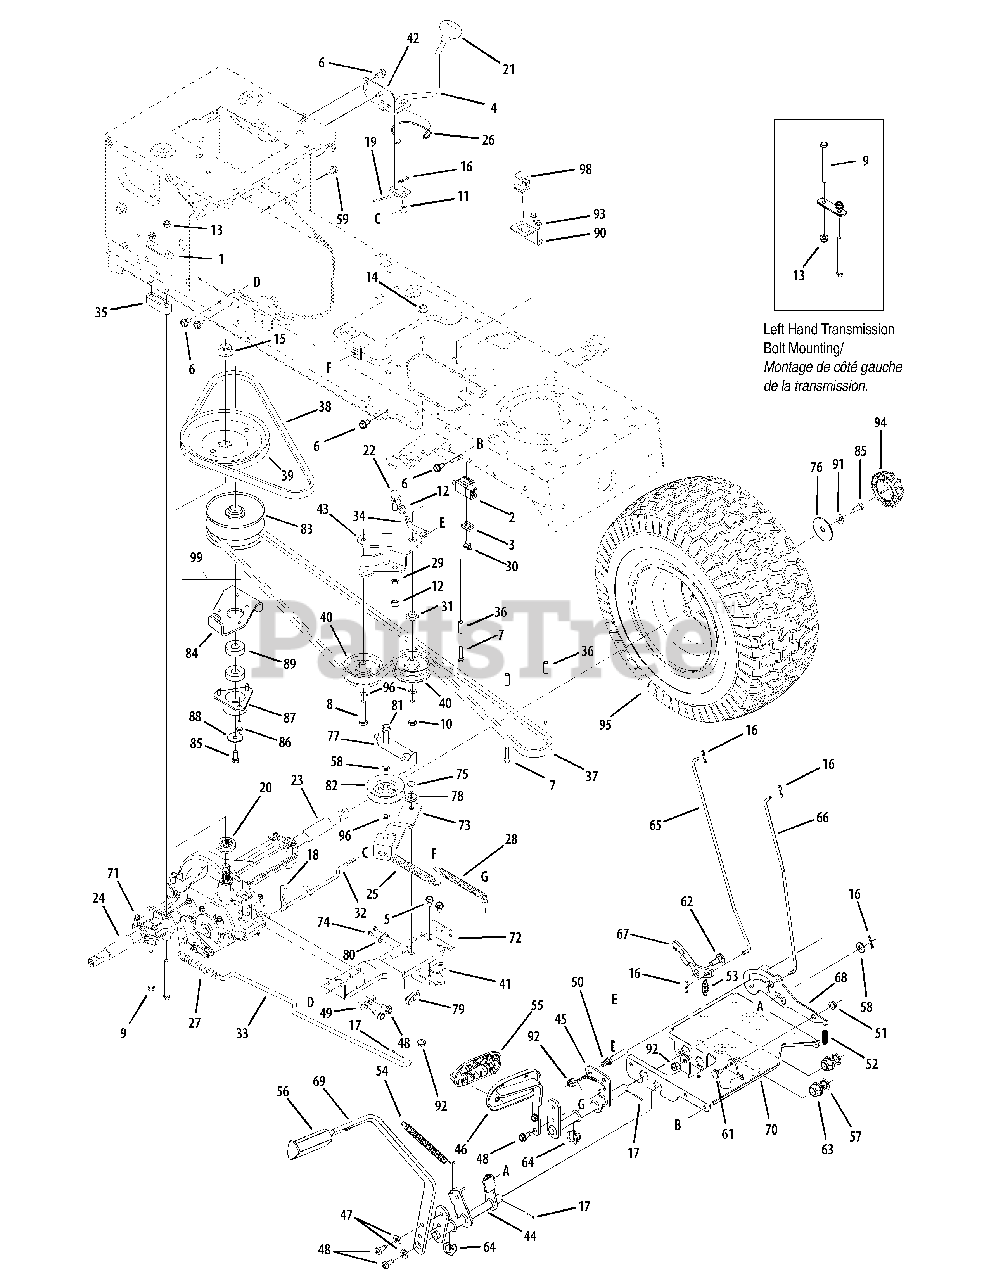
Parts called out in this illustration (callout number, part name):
2	Interlock Switch
3	Switch Plate
4	Shift Lever Ass’y
5	Hex Wash HD S-Tapp Scr 5/16-18 x .50
6	S-Tapp Scr 5/16-18 x .75
7	Hex Bolt 1/4-20 x 1.25
8	Hex L-Wash HD Scr 3/8-16 x 1.5
9	Hex Bolt 5/16-18 x 3.5" Lg.
10	Hex Bolt 3/8-16 x 2.0" Lg. Gr. 5
11	Adjustment ferrule
12	Hex Nut 3/8-24
13	Flange Locknut 5/16-18 Gr. F, Nylon
14	Flange Locknut 3/8-16 Gr. F
16	Int. Cotter Pin .072 x 1.13" Lg.
17	Cotter Pin 3/32 dia x 1.00 Lg.
18	Cotter Pin
19	Cotter Pin 1/8" Dia x 1.25
20	Pulley Hub 5/8" Spline
22	Drag Link Ball Joint
23	Sleeve, .758 x .821 x 3.3125
24	Sleeve, .758 x .821 x 2.4375
25	Extension Spring .62 dia. x 6.12
26	Complete Spring Clip
27	Extension Spring .59 x 4.0
28	Extension Spring, .50 Dia. x 6.37
29	L-Wash 3/8 ID
30	Hex AB-Tap Scr #10 x .50" Lg.
31	Shoulder Spacer
34	Idler Adjustment Rod, 3/8
35	Transaxle Spacer
36	Spacer .260 x .375 x 1.030 Lg.
37	Variable-speed Belt
38	Drive Belt
39	Pulley, V-Type, 7.25 dia.
40	Idler Pulley, Flat 2.75 OD
41	Shift Bracket
42	Shift Bracket F-N-R
47	L-Wash 5/16 ID
48	Hex Wash. Hd. Scr. 5/16-18 x .75 Lg.
49	Flat Washer .344 ID x .625 OD x .063
50	Pin 3/8-16 x 2.68 Lg.
51	Hex Flange L-Nut 5/16-18
52	Com pression Spring
53	Extension Spring, .50 OD x 1.41
54	Extension Spring, .50 Dia. x 6.37
55	AutoDrive Pedal Pad
57	Flat Washer .640 ID x 1.24 OD x .06
58	Flat Washer .38 ID x .87 OD x .09
59	Hex Hd Cap Scr. 5/16-18 x 2.0 Gr. 5
60	Hex Nut 516-18 Gr. 5
61	Shld. Scr .437 Dia x .162 Lg.
62	Shoulder Screw .500 x .25
63	Hex Flange Bearing .630 ID
64	Hex Flanged Bearing .628 ID
65	Brake Lock Rod
66	Cruise Control Rod
67	Cruise Control Latch
68	Lockout Bracket
71	Transmission Ass’y
72	Torque Bracket Assembly
74	Hex Wash HD AB S-Tapp Scr #8-.50
75	Hex Screw 3/8-16 x 1.25
76	Self-tapping Screw 5/16-18 x .625
78	Shoulder Spacer .884 ID x .190
79	Short Spring Switch
80	Insulator Nut Plate
81	Sems Screw 3/8-16 x 2.5
82	Idler Pulley, V-Type 5L x 3.06
83	Variable Speed Pulley Ass’y 4.75 OD
84	Pulley Bracket
85	Hex L-Bolt 5/16-24 x .75 Gr. 5
86	Hex Wash HD Bolt 1/4-20 x 1.50" Lg.
88	Flat Washer .22 ID x 1.25
89	Ball Bearing
92	Flange Lock-Nut 3/8-16 Gr. F Nylon
93	Hex Wash S-Tapp Scr 1/4-20 x .50
94	Hub Cap
96	Flat Washer .406 ID x .812 OD x .134
97	Cotter Pin 3/32 x .75
98	Switch
99	Variable Speed Pulley Ass'y
100	Flat Washer .350 ID x 1.59 OD x .062
